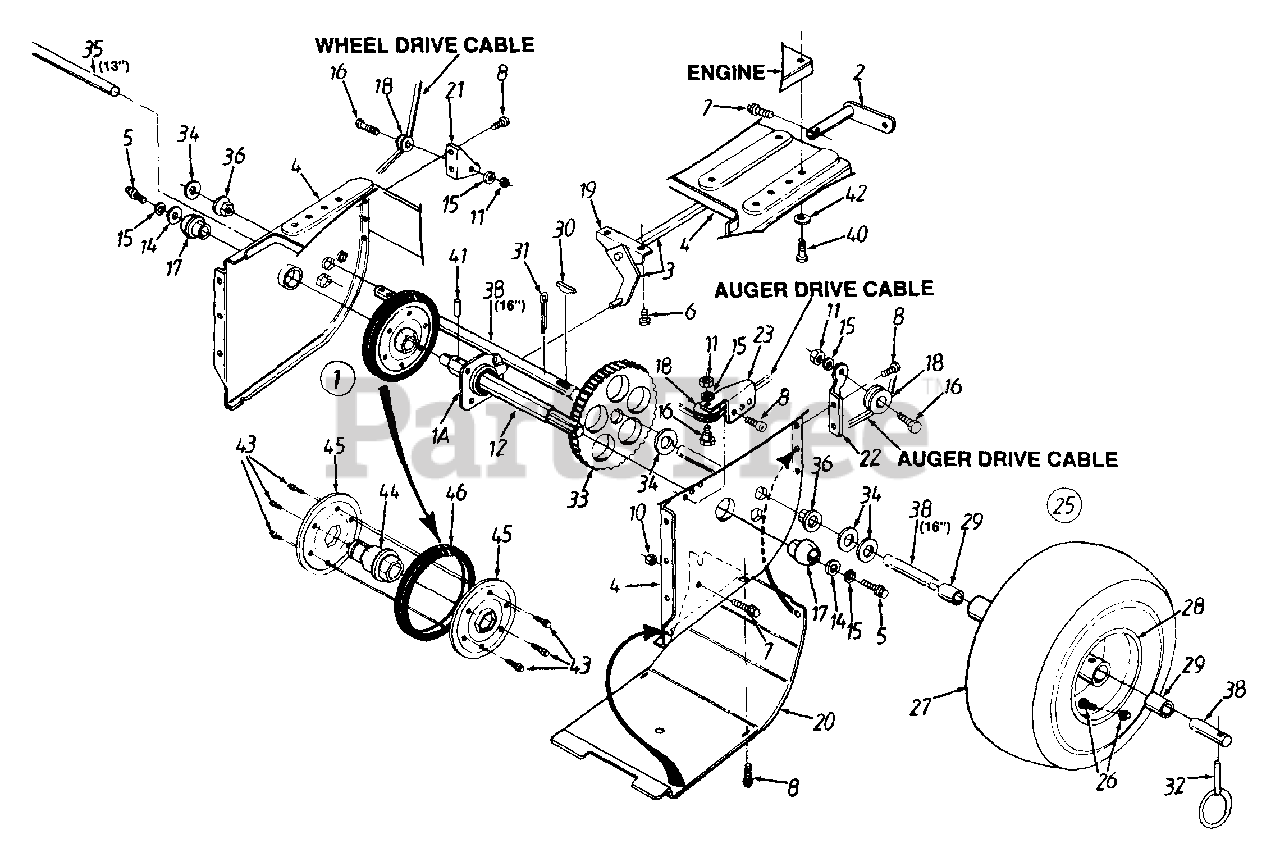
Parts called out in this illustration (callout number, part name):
1	Friction Wheel Ass'y. Comp.
1A	Friction Wheel Brg. Ass'y.
3	Shift Rod Ass'y.
6	Hex Tap Scr. 1/4-20 x .38" Lg.
7	Hex Wash. Hd. TT-Tap Scr. 1/4-20 x 1" Lg.
8	Torx Mach. AB-Tap Scr. 1/4 x .62" Lg.
10	Hex Nut 1/4-20 Thd.
11	Hex Jam Nut 1/4-20 Thd.
12	Gear Shaft
14	Fl-Wash. .265" I.D. x .938" O.D.
15	L-Wash. 1/4" I.D.
16	Shld. Bolt 5/16 Dia. x .35" Lg.
17	Ball Brg. w/Snap Ring
18	Cable Roller Guide
30	#9 Hi-Pro Key 3/16" x 3/4" Dia.
31	Cotter Pin 5/32" x 1-1/4" Lg.
32	Klik Pin
33	79 Tooth Gear
34	Fl-Wash. .76" I.D. x 1.49" O.D.
35	Wheel Axle
36	Hex Flange Brg. .752" I.D.
38	Wheel Axle
40	Hex Bolt 3/8-16 x 1.25"
41	Spr. Roll Pin 1.12" Lg.
42	Fl-Wash. .406" l.D. x 1" O.D.
43	Hex Wash. Hd. TT-Tap Scr. 1/4-20 x .5" Lg.
44	Friction Wheel Hub
45	Friction Plate
46	Friction Wheel Rubber
